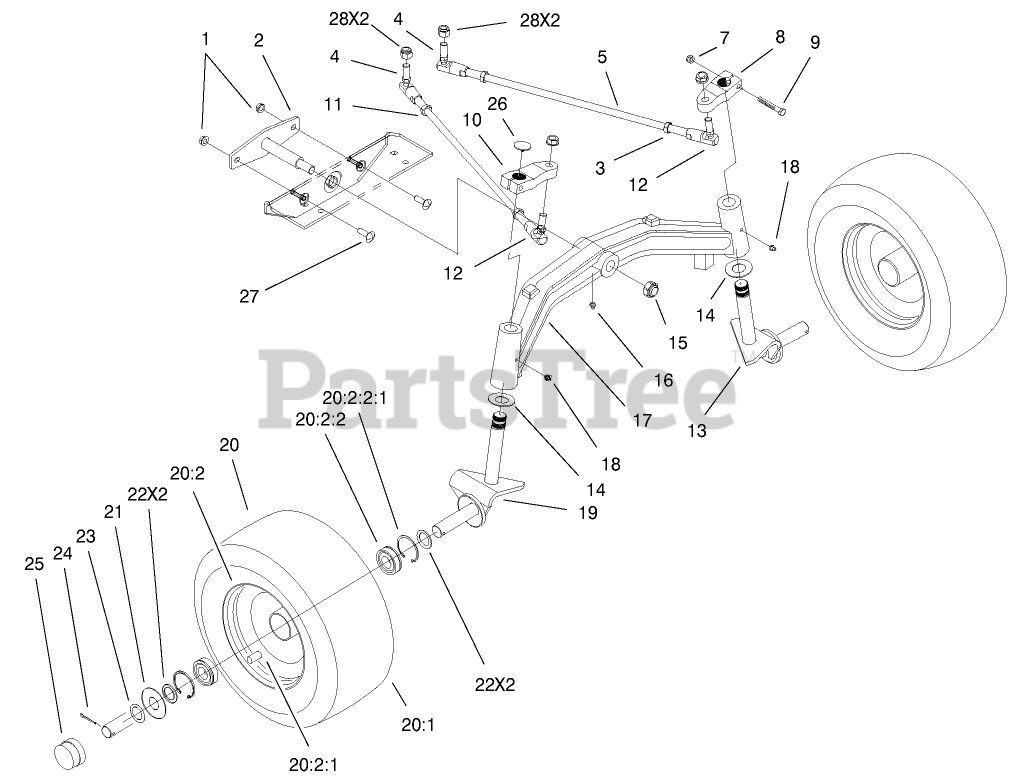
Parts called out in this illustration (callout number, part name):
1	NUT-LOCK, NI
3	NUT-JAM
4	BALLJOINT-THREAD, LH
5	ROD-TIE
7	NUT-LOCK, NI
8	ARM-STEERING, LH
9	SCREW-HH
10	ARM-STEERING, RH
11	NUT-HEX JAM LH
12	BALLJOINT-THREAD, RH
13	SPINDLE-LH
14	WASHER-THRUST
15	NUT-LOCK
16	FITTING-GREASE
17	AXLE-FRONT
18	FITTING-GREASE
20	ORDER COMPONENT PARTS
20:2	RIM ASM
20:2:1	VALVE
20:2:2	BEARING
21	WASHER-WHEEL
23	WASHER
24	PIN-COTTER
25	CAP-DUST
26	CAP - SPINDLE
27	BOLT-CARR
28	NUT-LOCK
